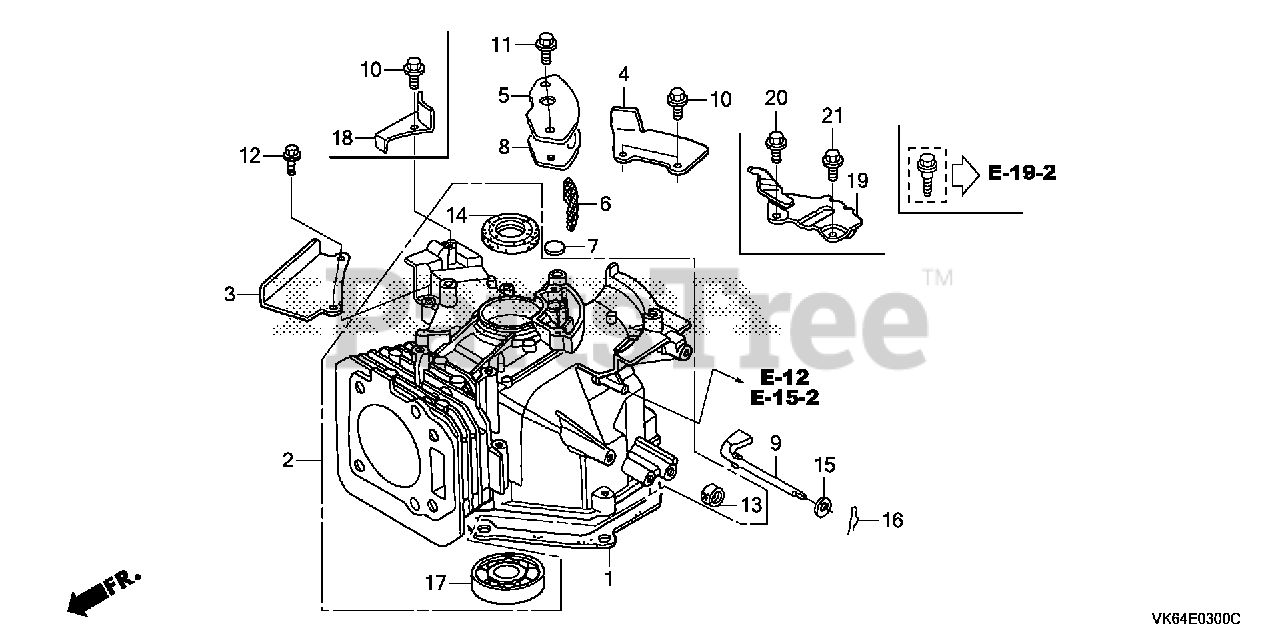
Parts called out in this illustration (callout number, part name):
1	GASKET, OIL PAN
2	CYLINDER ASSY.
3	PLATE, GUIDE
4	PLATE A, GUIDE
5	COVER, BREATHER
6	FILTER, BREATHER
7	VALVE, BREATHER
8	GASKET, BREATHER COVER
9	SHAFT, GOVERNOR ARM
10	BOLT, FLANGE (6X12) (CT200)
11	BOLT, FLANGE (6X14)
12	BOLT, FLANGE (6X20) (CT200)
13	OIL SEAL (6X11X4)
14	OIL SEAL (25X38X7)
14	OIL SEAL (25X38X7) (ARAI)
15	WASHER, PLAIN (6MM)
16	PIN, LOCK (8MM)
17	BEARING, RADIAL BALL (6205)
